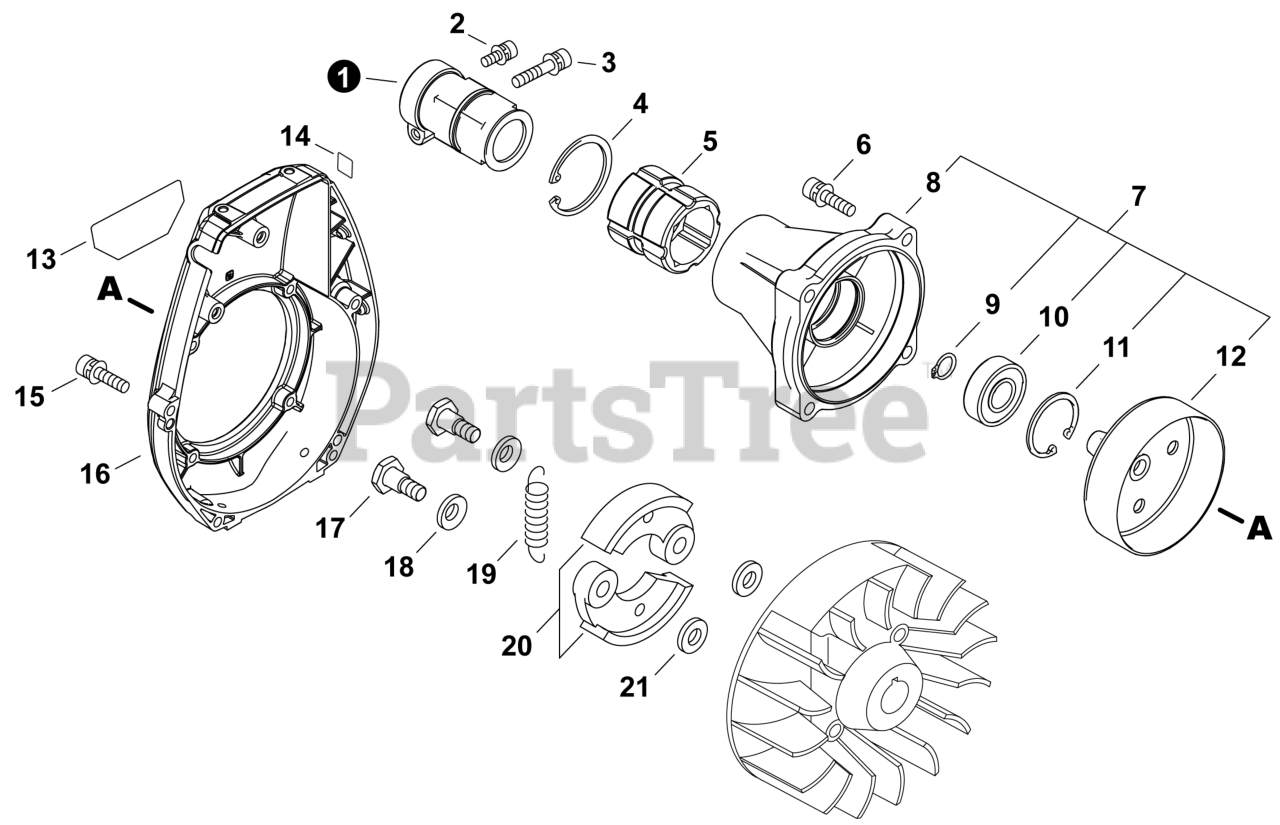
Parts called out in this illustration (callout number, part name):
1	CUSHION, MAIN PIPE
2	BOLT 5x12
3	BOLT 6x30
4	RING, SNAP 45
5	CUSHION
6	BOLT 6x30
7	CASE ASSY, CLUTCH
8	CASE, CLUTCH
9	RING, SNAP 15
10	BEARING, BALL
11	RING, SNAP 35
12	DRUM, CLUTCH
13	LABEL - MODEL B451
14	LABEL - CAUTION - HOT
15	BOLT 5x25
16	COVER, FAN
18	WASHER, WAVE
19	SPRING, CLUTCH
20	CLUTCH SHOE SET
21	WASHER 8.2x17x1.6
